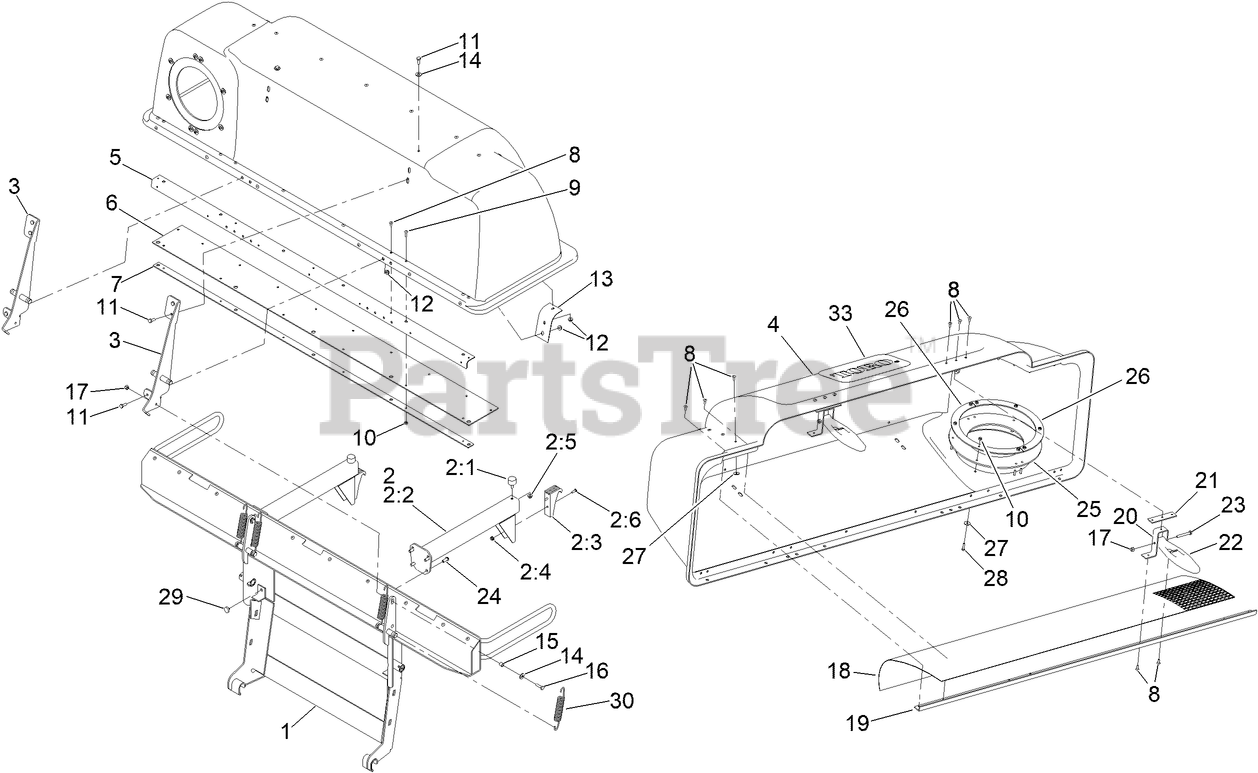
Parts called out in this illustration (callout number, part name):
1	FRAME-TRIPLE BAGGER
2	BAG SUPPORT ASM
2:1	BUMPER
2:2	SUPPORT-BAG
2:4	NUT-HF
2:5	NUT-HF
2:6	SCREW-PPH
4	HOOD ASM
5	STIFFENER-BAGGER, TOP
6	SEAL-HINGE
7	PLATE-BACKING
8	RIVET-BLIND
9	SCREW-HEAD, TRUSS
10	NUT-LOCK, NI
11	SCREW-HH
12	NUT-HF
13	REINFORCEMENT-HOOD, BAGGER
14	WASHER-FLAT
15	SPACER
16	SCREW-HH
17	NUT-LOCK, NI
18	HOOD ASM
19	SUPPORT-SCREEN
20	BRACKET-MOUNT
21	PLATE-LATCH, REINFORCEMENT
23	SCREW-HH
24	SCREW-HSBH
25	SEAL-TUBE
26	CLAMP-SEAL
27	WASHER-FLAT
28	SCREW-PPH
29	BUMPER
30	SPRING-EXTENSION
33	DECAL
